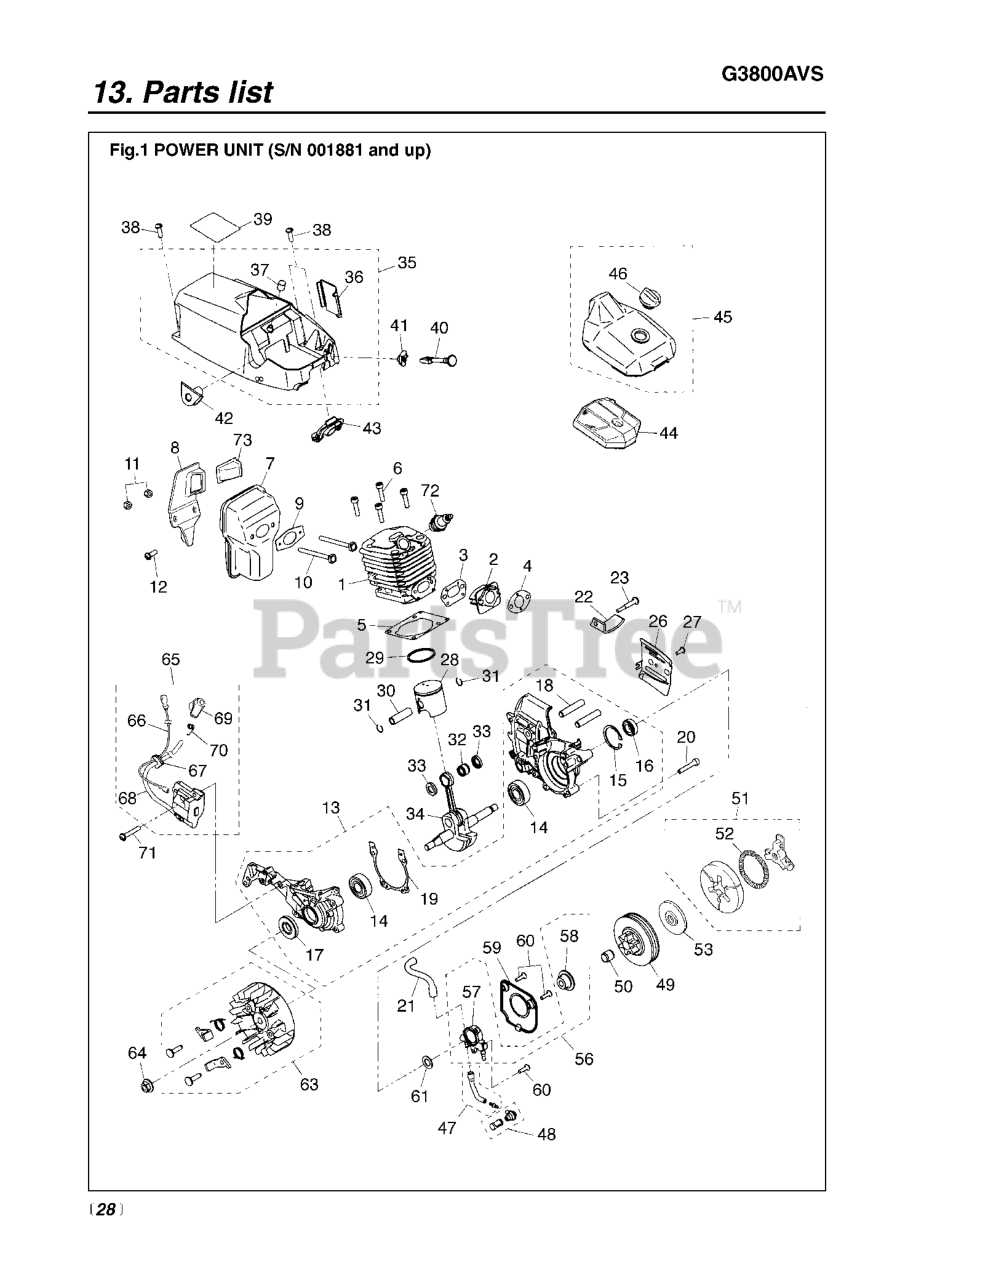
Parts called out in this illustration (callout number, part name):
1	CYLINDER
2	INSULATOR
9	GASKET, MUFFLER
12	RP_SCREW
13	CRANKCASE ASSY
14	BEARING
18	STUD BOLT
21	PIPE
26	PLATE(A)
27	SCREW
29	RING, PISTON
30	PISTON PIN
32	ROLLER BEARING
33	WASHER
35	COVER COMPLETE
40	ROD.CHOKE
45	COVER, CLEANER COMP
47	PIPE IN COMP.(RPLS 848C306731)
49	DRUM.3/8-6
50	ROLLER BEARING
51	CLUTCH ASSY(RPLS T210051200)
53	PLATE
57	OIL PUMP
58	OIL PUMP
60	SCREW
64	NUT
67	GROMMET
70	SPRING PLUG
71	SCREW
73	ARRESTER, SPARK
